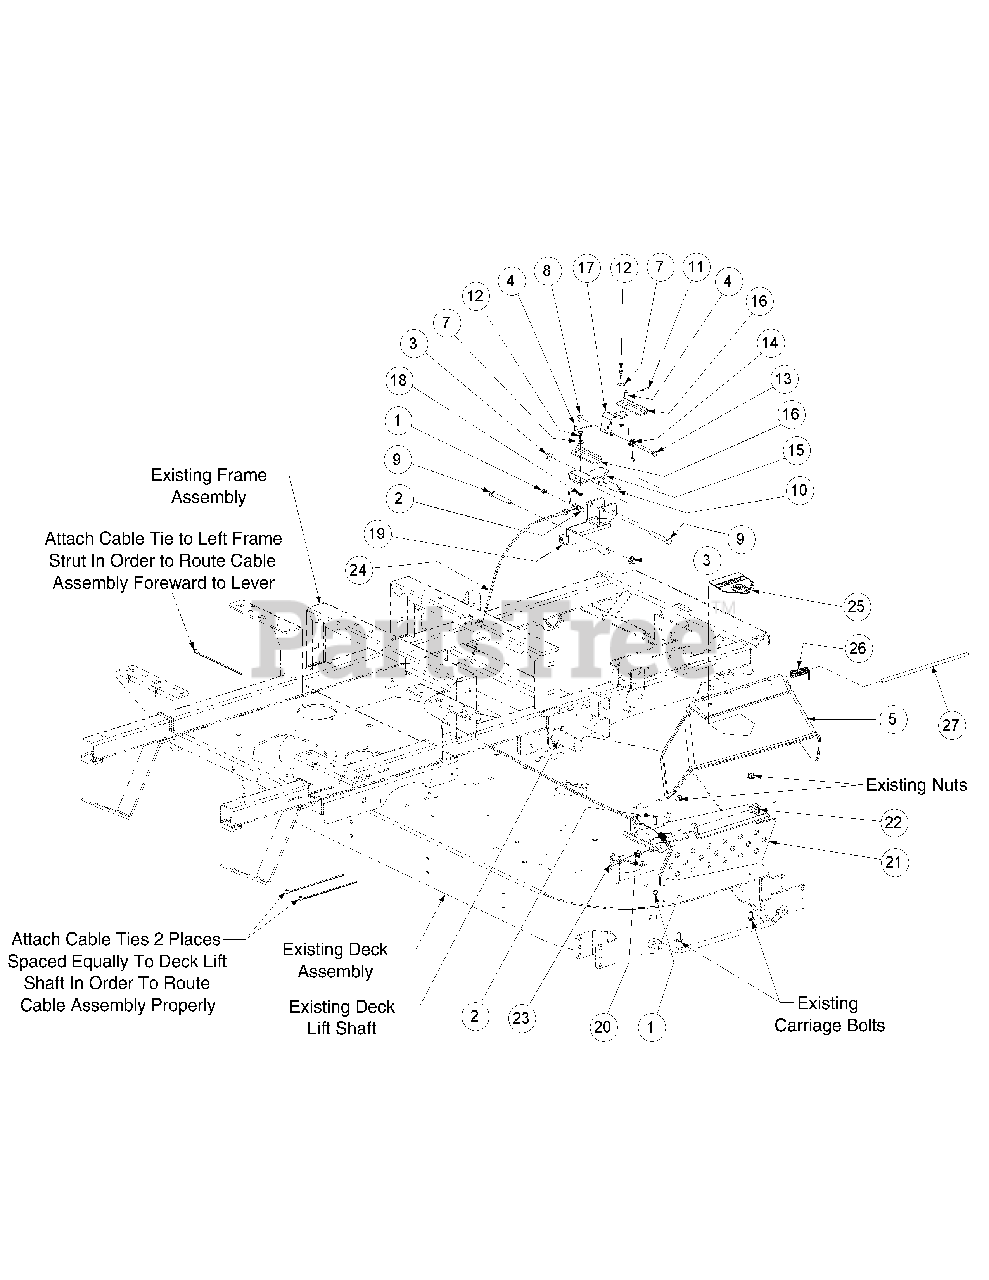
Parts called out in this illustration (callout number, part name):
1	Lock Nut, Nylon Insert, 1/4-20
2	Screw, Hex, Cap, 1/4-20 x .75
3	Hex Nut, Flange Lock, 3/8-16
4	Clevis Pin, 1/4 x 1/2, SS
5	Chute Deflector
7	Bell Washer, .265 x 0.75 x 0.062
8	Hex Flange Lock Nut, 5/16-18
9	Hex Head Capscrew, 3/8-16 x 2.75
10	Spacer, .39 ID x .63 OD x 1.75
11	Cotter Pin, .072 x 1.12 Lg
12	Shoulder Bolt, 1/4 x 1/4, SS
13	Hex Head Capscrew, 5/16-18 x 2.5
14	Deck Lift Spring
15	Foot Pedal Latch Lever Assembly
16	Rate Plate Pad
17	Foot Pedal Latch Assembly
18	Nut w/ Star Washer, 10-24
19	Bracket Engage Cable Weldment
20	Restrictor Discharge Spring
21	Restrictor Discharge Weldment
22	Chute Deflector Bracket Weldment
23	Restrictor Support Weldment
24	Restrictor Discharge Cable Assembly
25	Decal, Danger, Hands & Feet
26	Torsion Spring, 0.4 ID x 2.16 LG.
27	Chute Deflector Rod
